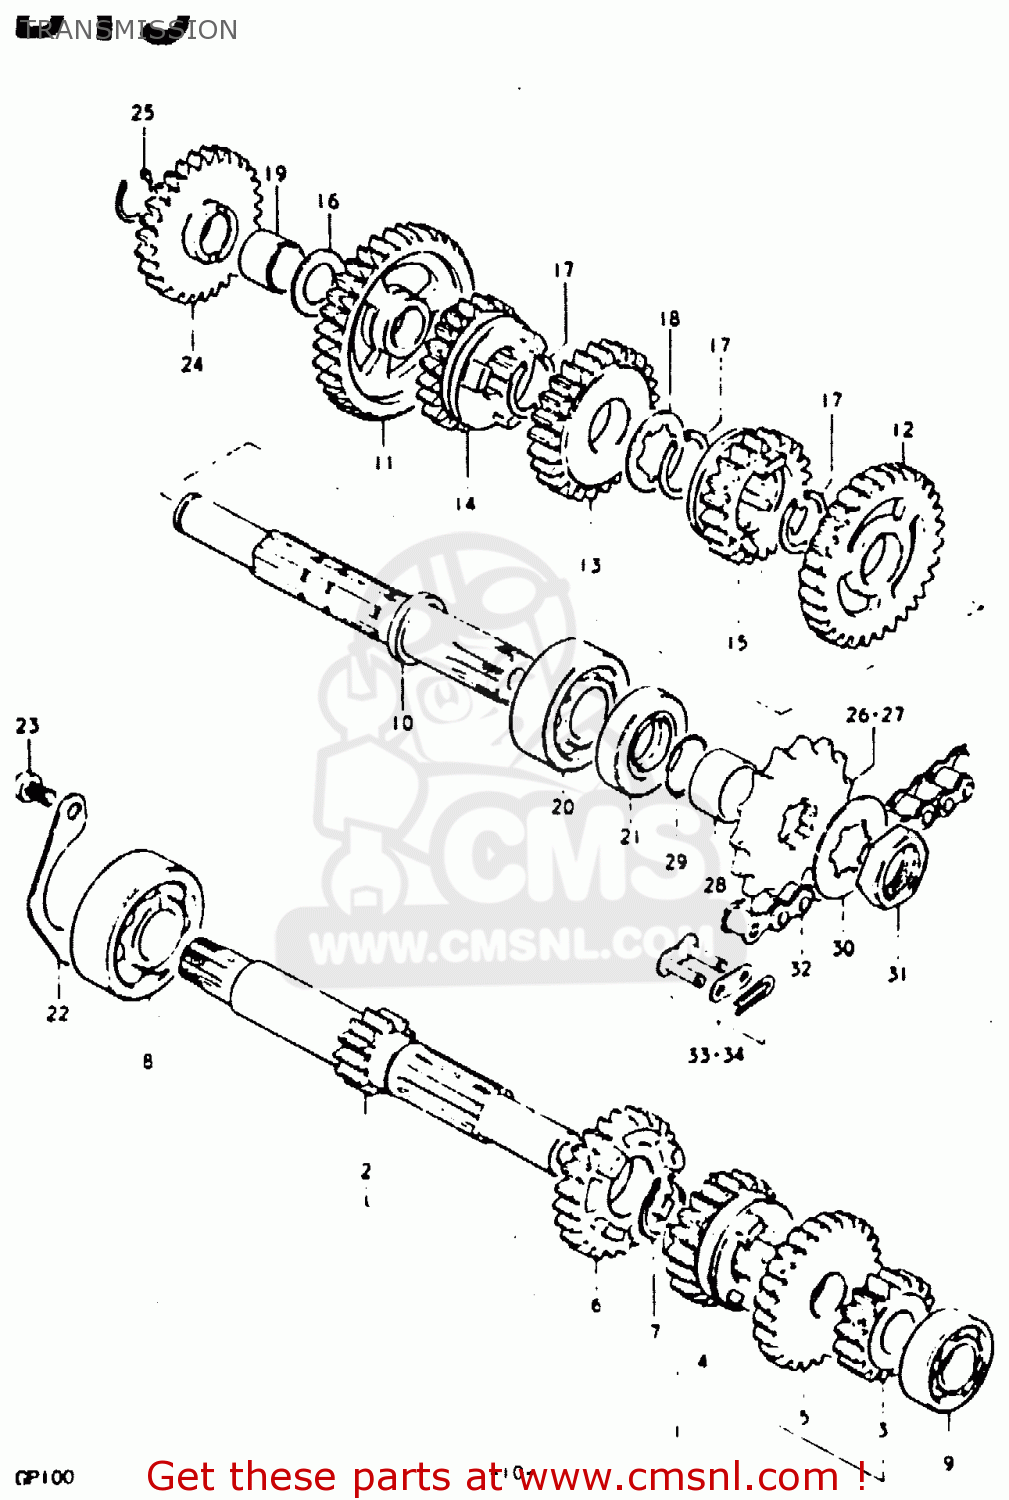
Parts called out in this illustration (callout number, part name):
1	SHAFT, COUNTER
2	COUNTER SHAFT (NT:11)
3	GEAR,SECOND DRIVE
4	GEAR, 3RD DRIVE (NT:20)
5	GEAR, 4TH DRIVE (NT:23)
6	GEAR, 5TH DRIVE (NT:25)
7	CIRCLIP
8	Bearing
9	BEARING
10	SHAFT, DRIVE
11	GEAR,1ST DRIVEN
12	GEAR, 2ND DRIVEN (NT:29)
13	GEAR, 3RD DRIVEN (NT:25)
14	GEAR, 4TH DRIVEN (NT:22)
15	GEAR, 5TH DRIVEN (NT:20)
16	WASHER,THRUST
17	CIRCLIP
18	WASHER
19	BUSH
20	Bearing
21	SEAL,OIL(25X40X7)
22	RETAINER,CNTR SHAFT BEARING
23	SCREW 6X12
24	GEAR,KICK STARTER IDLE
25	CIRCLIP,15MM
26	SPROCKET,ENGINE
27	SPROCKET,ENGINE
28	SPACER(20X25X12.5)
29	O RING(D:1,ID:19.5)
30	WASHER,LOCK
31	NUT
32	CHAIN ASSEMBLY,DRIVE
33	JOINT ASSEMBLY,CHAIN
34	JOINT ASSEMBLY,CHAIN
